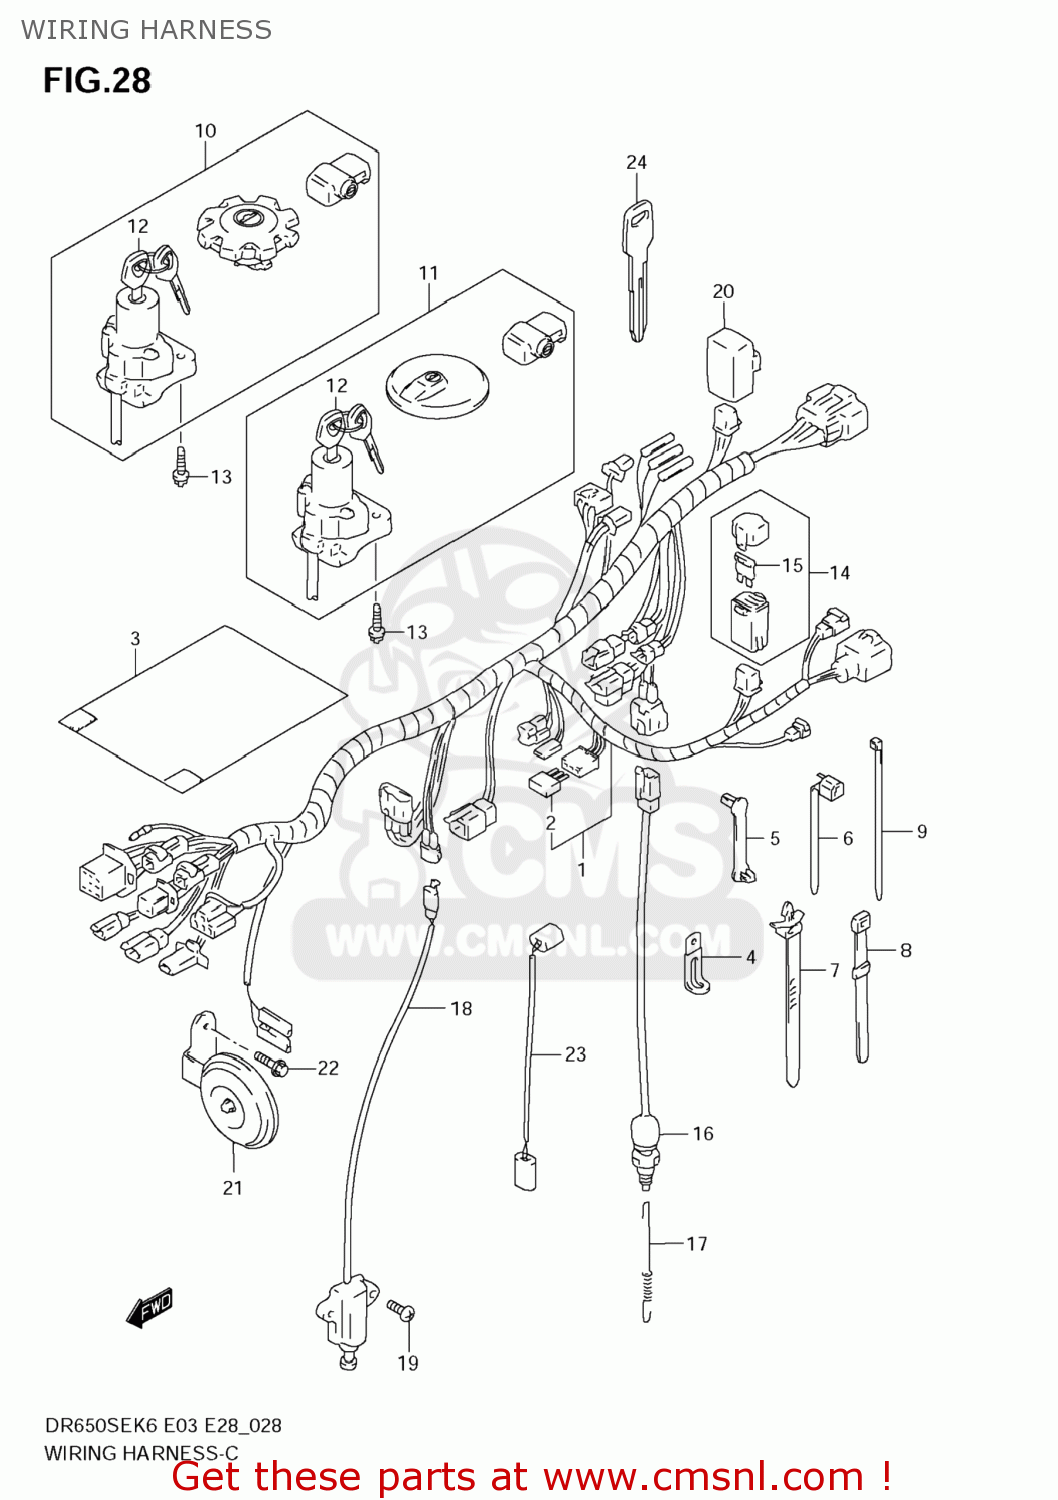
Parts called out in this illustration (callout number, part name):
1	HARNESS,WIRING
2	DIODE(STANLEY DE8804)
3	COVER,WIRING HARNESS
4	CLAMP(L:45)
5	CLAMP(L:33)
6	CLAMP(L:95)
7	CLAMP(L:90)
8	CLAMP(L:120)
9	CLAMP(L:100)
10	LOCK SET
11	LOCK SET
12	LOCK ASSY,STEERING
13	BOLT(8X20)
14	BOX ASSY,FUSE
15	FUSE(10A)
16	SWITCH ASSY,STOP LAMP
17	SPRING
18	SWITCH ASSY,SIDE STAND
19	SCREW
20	RELAY ASSY
21	HORN ASSY
22	BOLT
23	WIRE,THROTTLE SENSOR
24	KEY,BLANK
